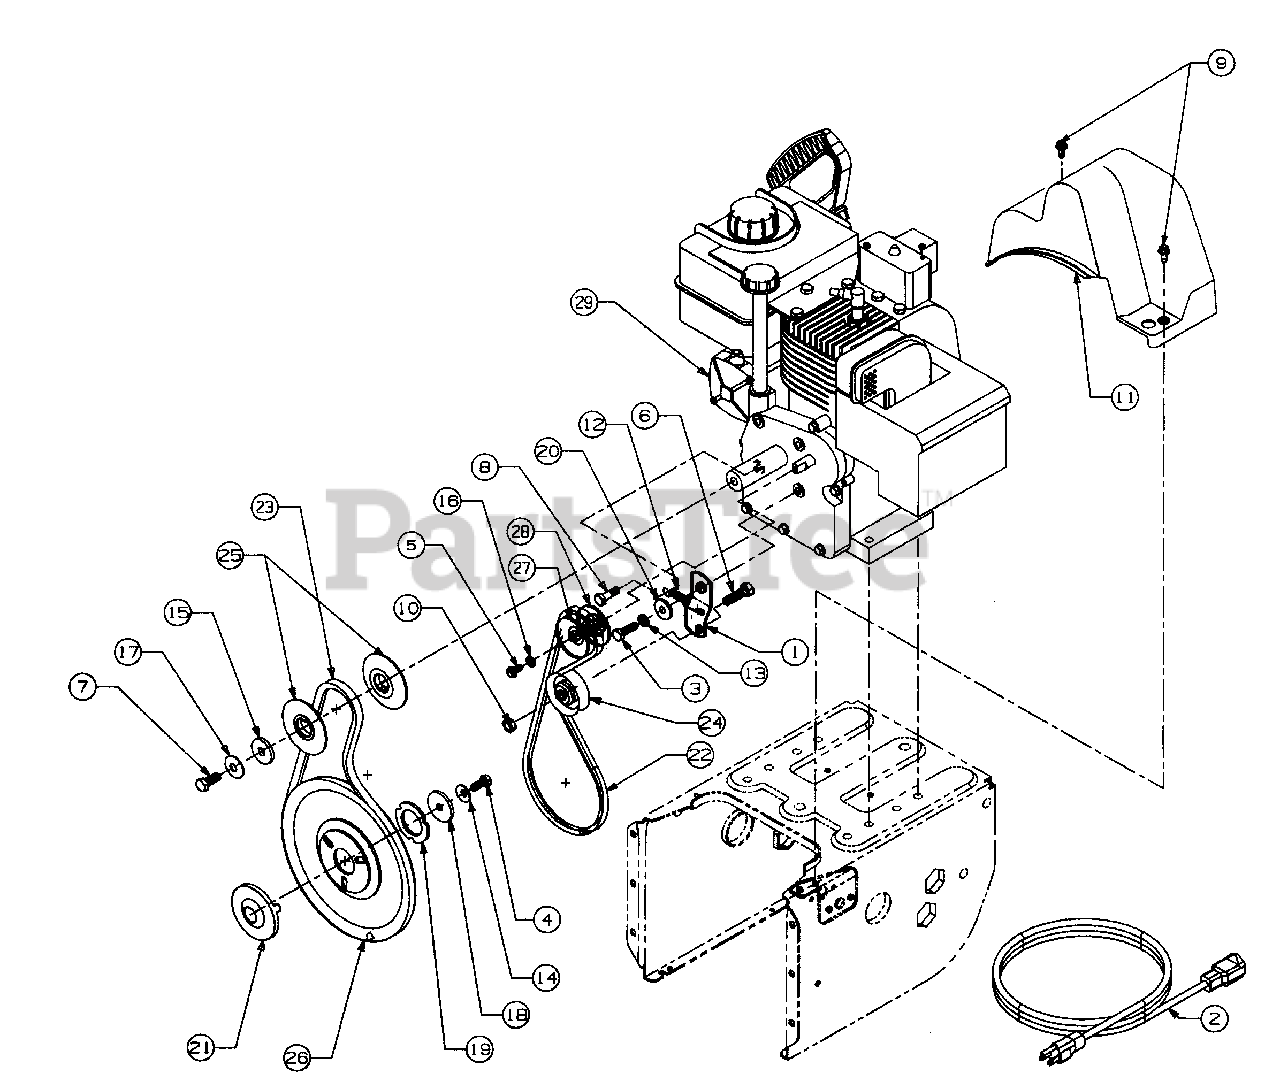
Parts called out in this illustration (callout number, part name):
3	Screw-Hex
4	Screw-Hex
5	Screw-Hex
6	Screw-Hex
7	Screw-Hex
8	Screw-Hex
9	Screw-Hex
10	Nut-Hex
11	Cover-Belt
12	Spring
13	Washer-Lock
14	Washer-Bell
15	Washer-Flat
16	Washer-Lock
17	Washer-Lock
18	Washer-Flat
19	Washer
20	Spacer
21	Adapter-Pulley
22	V-Belt
23	V-Belt
24	Idler-Flat
25	Pulley-Half
26	Pulley
27	Pulley-Half
28	Pulley-Half
29	Electric Start Kit
